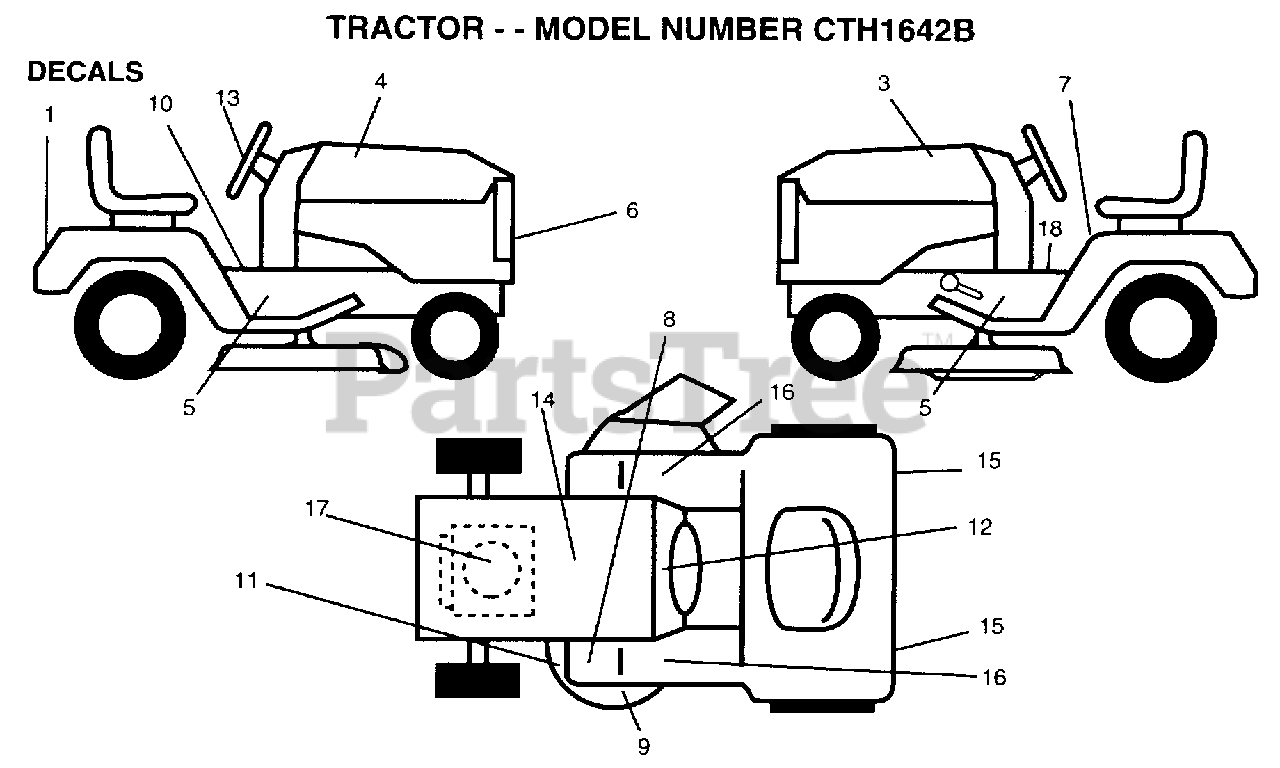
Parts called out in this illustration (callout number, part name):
1	DECAL.FEND.RALLY
3	DECAL HOOD LH
4	DECAL.HOOD.RH
5	DECAL.CHAS.42.HYD
6	DECAL.GRILLE.RLY
7	DECAL
10	DECAL BRAK PARK
11	DECAL
12	DECAL.DASH.INST.
13	DECAL.WHL.STR.RLY
14	DECAL.BTRY.DANGER
15	REFLECTOR-TAIL YT
16	FOOTREST PAD
17	DECAL, HP ENGINE
18	DECAL SADLE HYDRO
